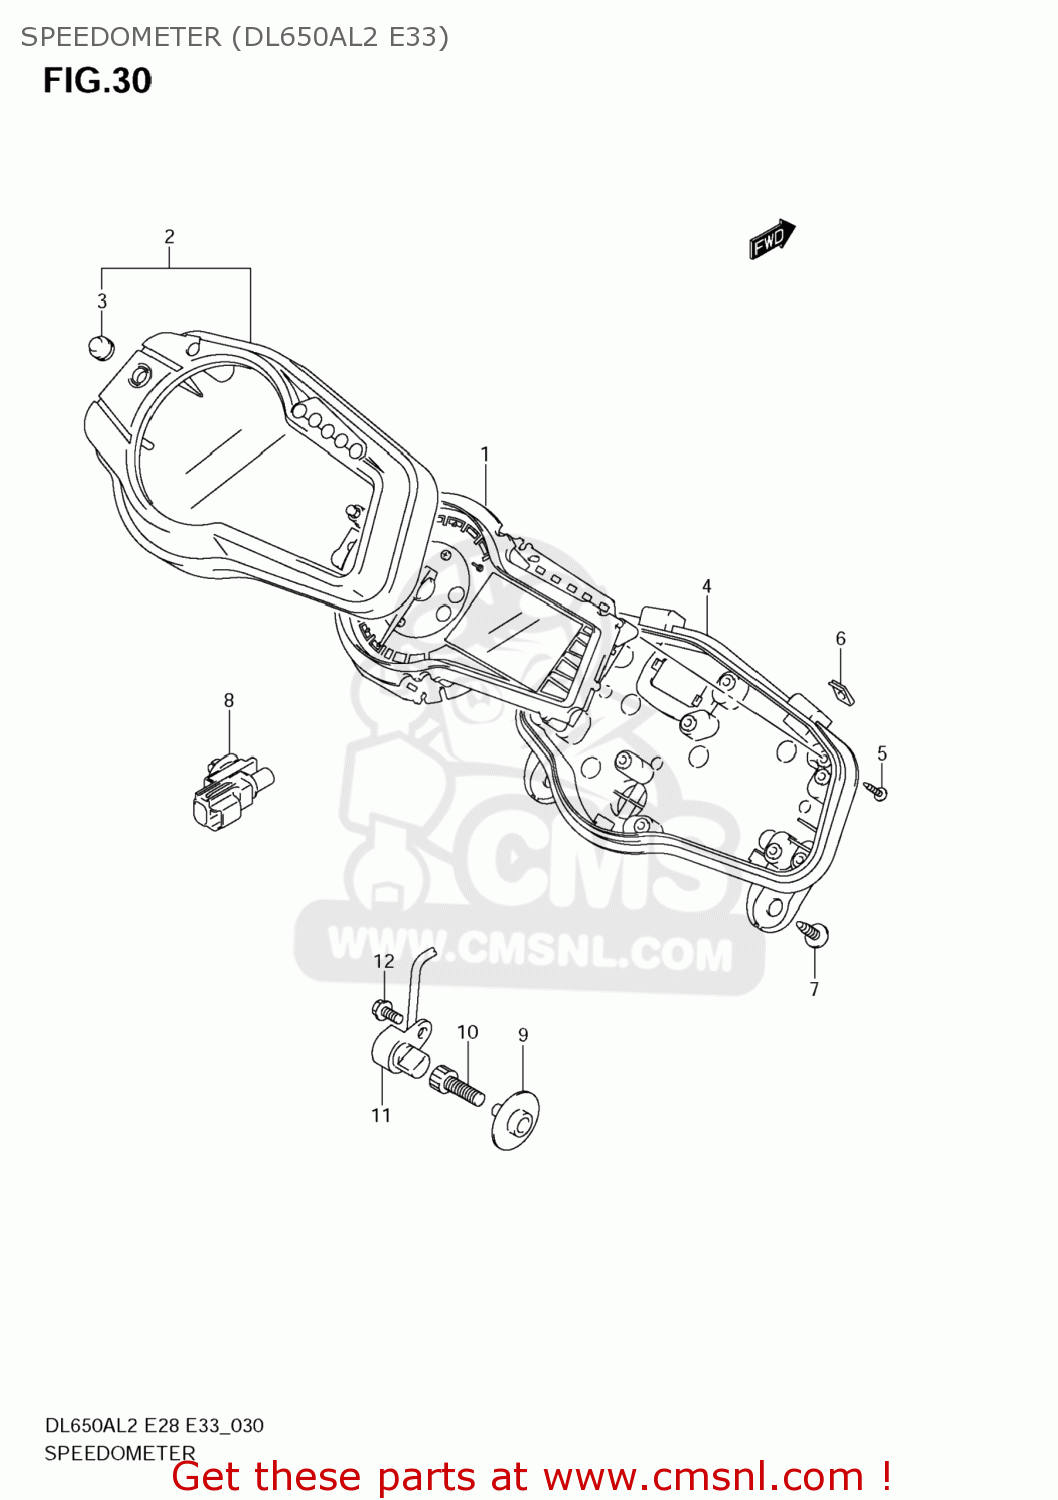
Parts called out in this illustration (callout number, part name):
1	SPEEDOMETER
2	CASE ASSY,UPR
3	RUBBER,SWITCH
4	CASE ASSY,LWR
5	SCREW(3X16)
6	NUT
7	SCREW
8	SENSOR,AIR TEMP
9	ROTOR,SPEED
10	BOLT
11	SENSOR,SPEED
12	BOLT
